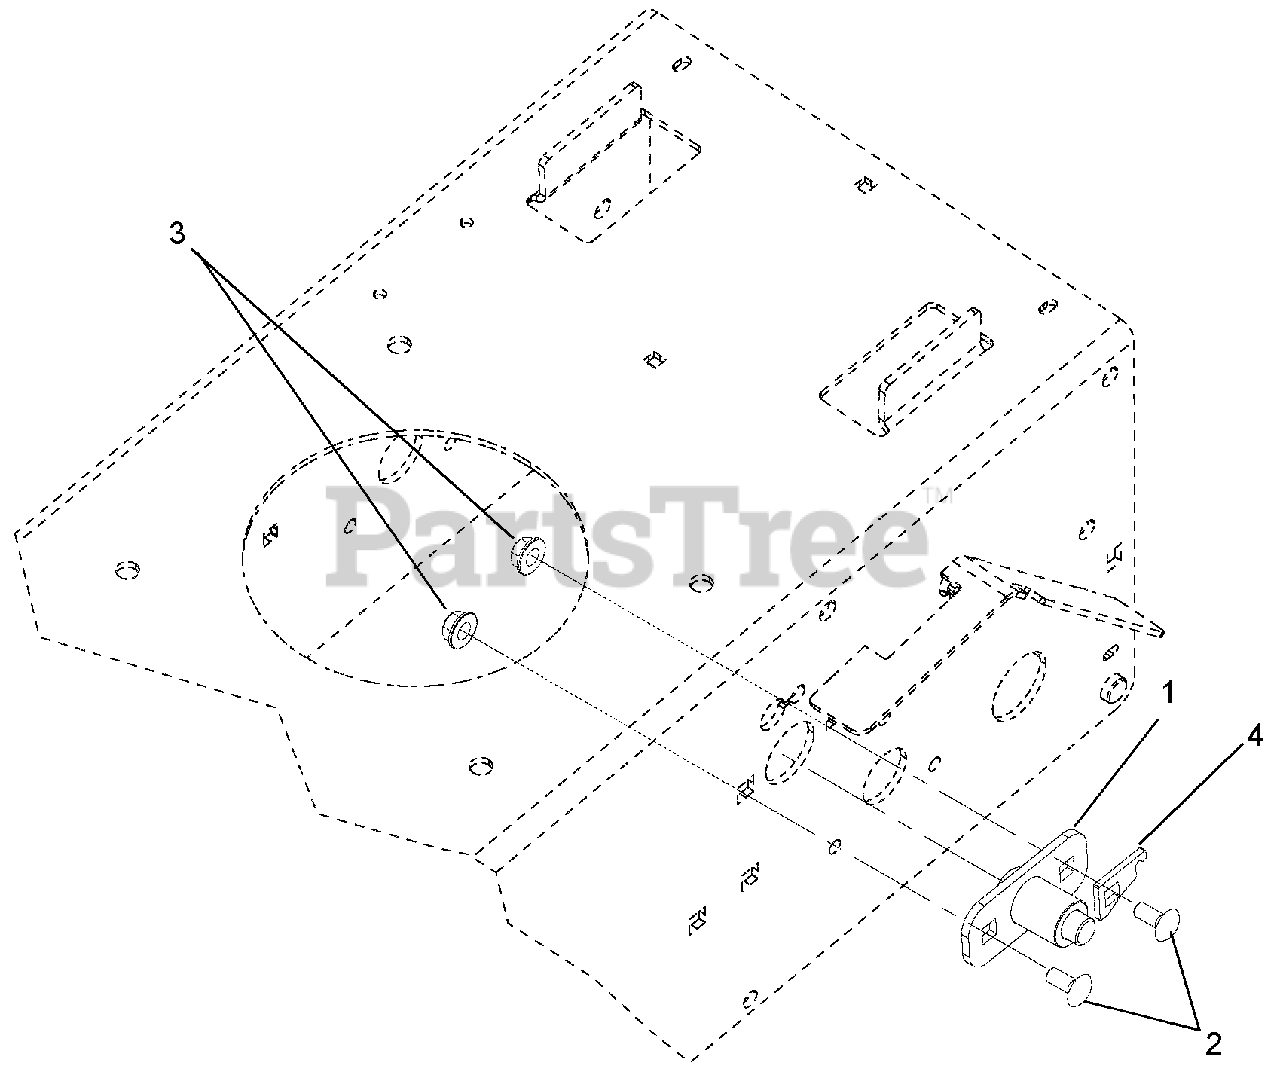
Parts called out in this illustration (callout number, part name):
1	KIT, WAW PIN BRAKE
2	@BLT-RDHDSQNK .38-16X1.25 G5YZ
3	@NUT-SPNLK-FLG .375-16 YWZC
4	EXTENDER, SPRING
